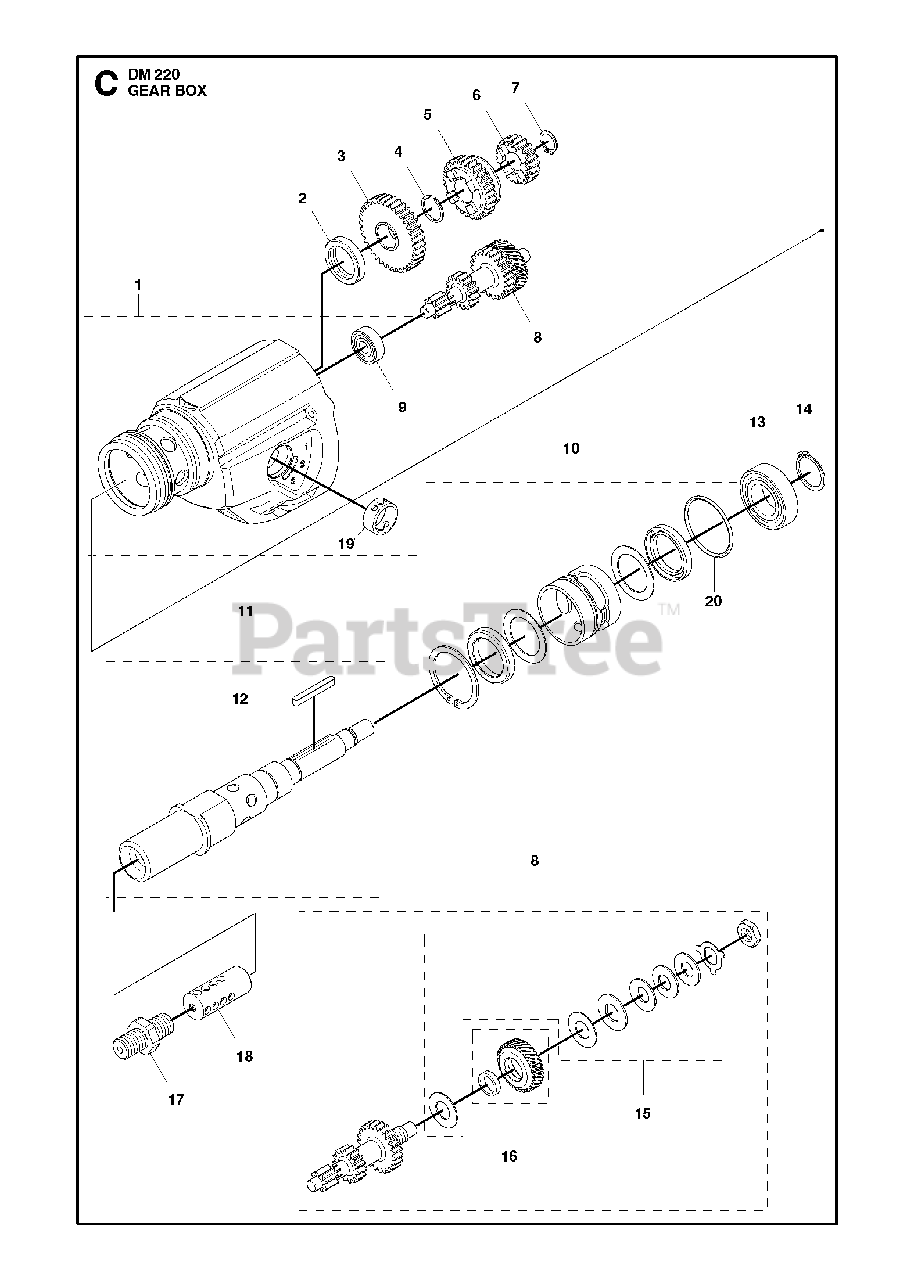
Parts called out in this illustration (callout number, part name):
1	GEAR HOUSING ASSYValid before S/N, 20153300021
10	COLLECTORValid before S/N 20153300021
12	KEYValid before S/N 20153300021
20	O-RINGOnly included in 577 24 42-02
